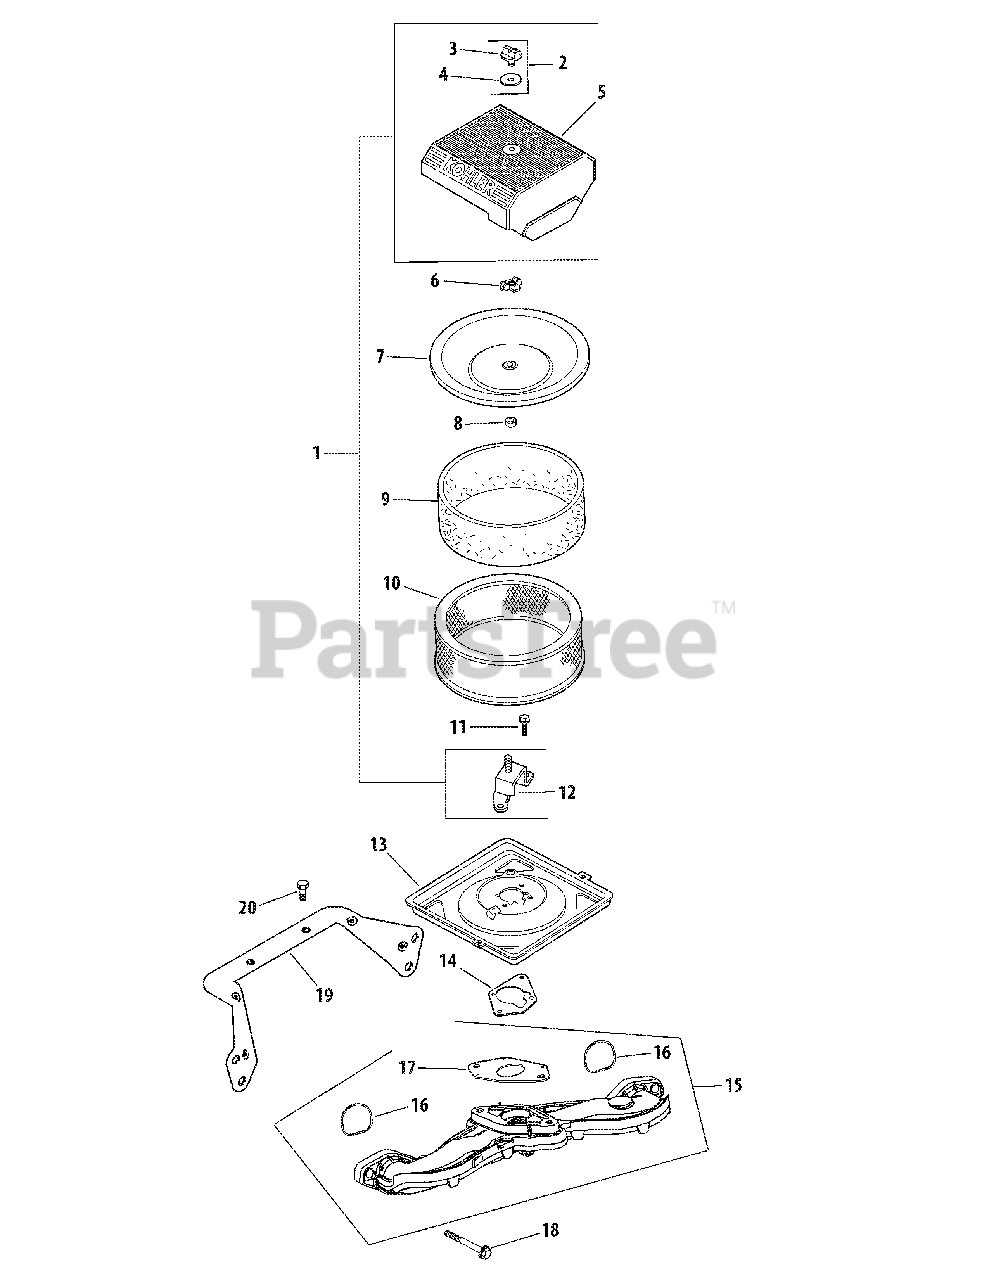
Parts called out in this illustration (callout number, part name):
1	Kit, Air Cleaner Cover (Incl. 2-5, 12)
2	Kit, Knob w/Seal (Incl. Ref #2,3)
4	Seal, Air Cleaner Cover Knob
5	Cover, Air Cleaner
7	Cover, Inner Air Cleaner
8	Seal, Inner Air Cleaner
9	Precleaner, Element - Includes Ref. 10
10	Element, Air Cleaner - Includes Ref. 9
11	Screw, Hex Flng, M6 x 1.0 x 16
12	Bracket, Air Cleaner Base
13	Base, Air Cleaner
14	Gasket, Air Cleaner Base
15	Manifold, Intake (Includes 16,17)
16	O-Ring, Intake Manifold
17	Gasket, Carburetor
18	Screw, Hex Flange, M6 x 1.0 x 40
19	Bracket, Air Cleaner Base
20	Screw, Hex Flange, M5 x .8 x10
